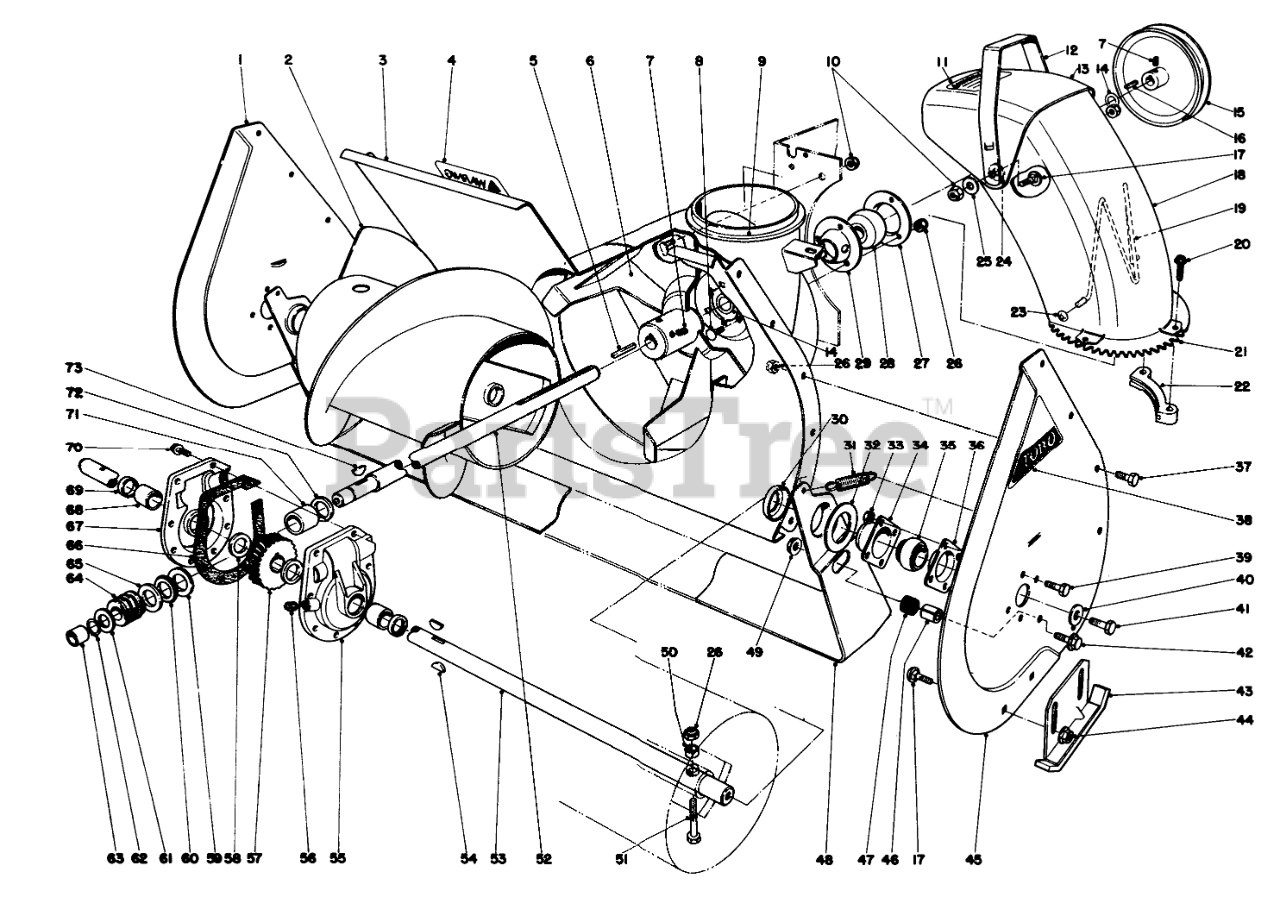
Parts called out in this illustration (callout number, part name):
1	Side Plate Right
2	Auger Right
3	Auger Housing
4	Decal
6	IMPELLER WA RO
7	Set Screw
8	BOLT-CARR
9	CHUTE RING
10	NUT-LOCK, CONE
11	CHUTE WARNING DECAL
12	DEFLECTOR HANDLE B
13	Chute Deflector
14	WASHER
15	IMPELLER PULLEY
16	SQUARE KEY
17	SCREW-CARR
18	Chute
19	WIRE-CHUTE
20	SPECIAL SCREW
21	Chute Swivel Gear
22	CHUTE RETAINER
23	NUT-PUSH
24	WASHER-RUBBER
25	WASHER-BELLEVILLE
26	NUT-LOCK, CONE
27	FLANGE-CUP, BEARING
28	Ball Bearing
29	FLANGE-CUP, BEARING
30	Positioner-Scraper
31	SPRING-TENSION
32	SCRAPER BLADE SPACER
33	NUT-LOCK, CONE
34	BEARING-FLANGE, FRONT
35	BEARING
36	BEARING-FLANGE, REAR
37	SCREW-HH
38	AUGER SIDE PLT DECAL
39	SCREW-HH
40	WASHER
41	SCREW-HH
42	SCREW-HHF
43	Skid
44	NUT-HHF, WHIZ
45	Sideplate Auger Left
46	SCRAPER STOP SPACER
47	SCRAPER STOP CUSHION
48	24 SCRAPER BLD
49	NUT-HF
50	SPACER-HUB, AUGER
51	Auger Bolt
52	Impeller Shaft
53	24 AUGER SHAFT
54	KEY-WOODRUFF
55	Gear Case Assembly L.H. (Include Ref. # 68 & 69)
56	PLUG-PIPE, SQH
57	GEAR-WORM, 27T
58	WASHER-THRUST
59	WASHER-THRUST
60	BEARING-THRUST
61	WASHER-THRUST
62	Ring-Snap
63	BUSHING
65	THRUST-WASHER
66	Gasket
67	Gear Case Assembly R.H. (Include Ref. #68 & 69
68	BUSHING
69	SEAL-OIL
70	SCREW-HWHTF
71	BUSHING-SPECIAL
72	RING-QUAD
73	KEY-WOODRUFF
